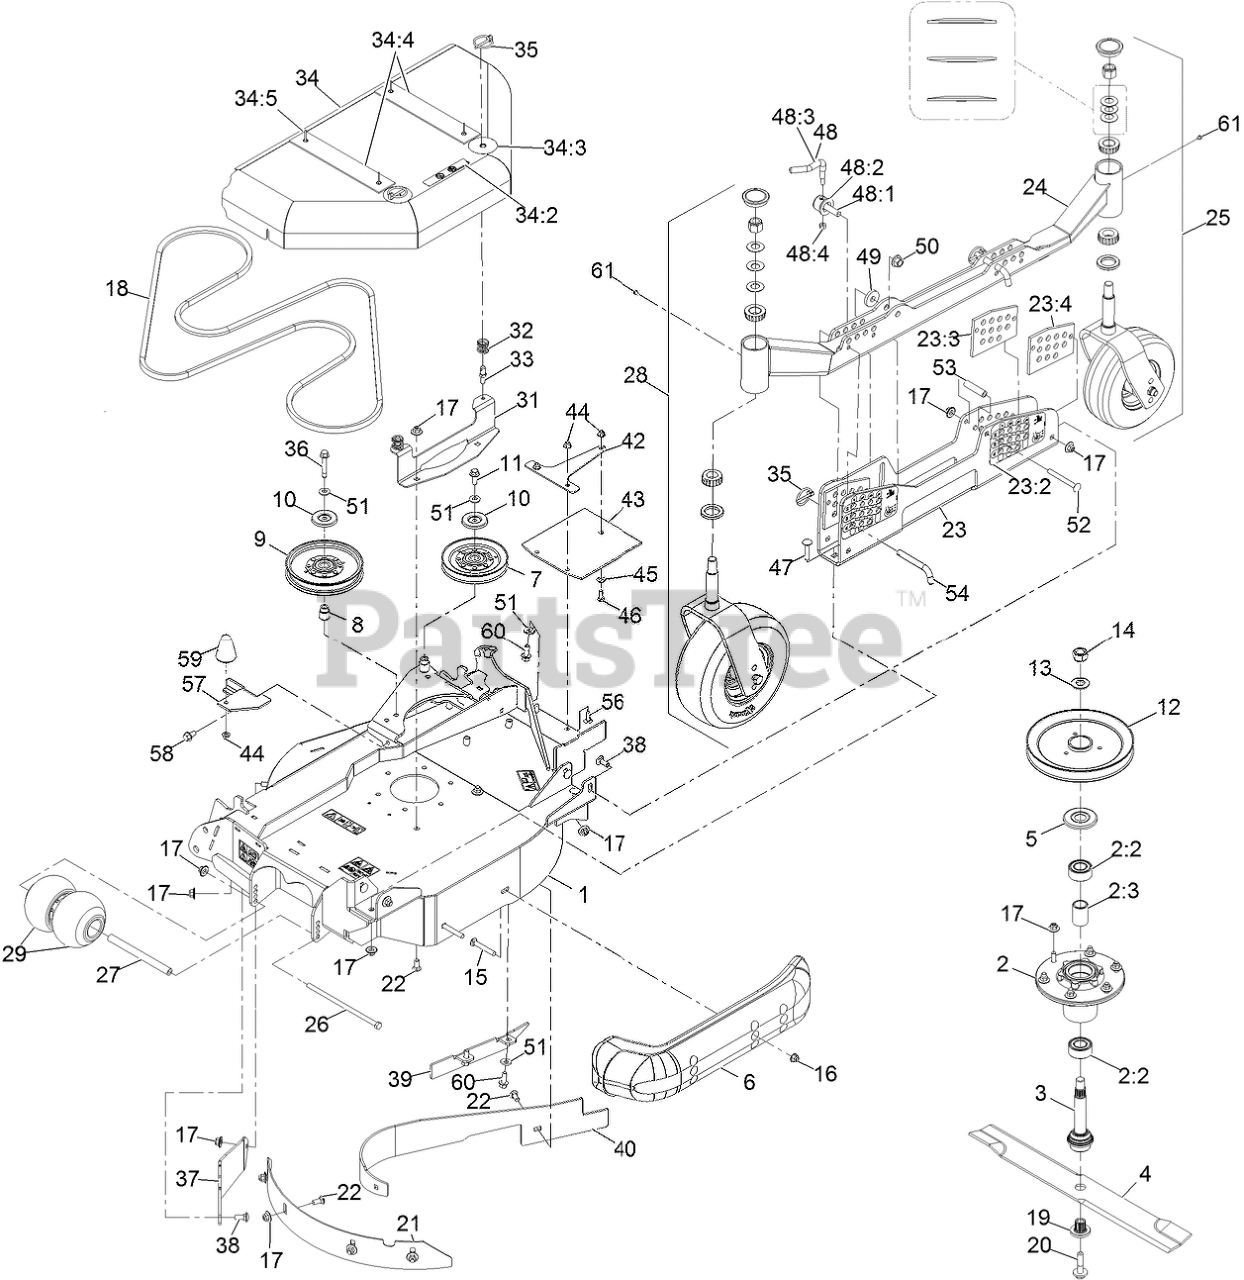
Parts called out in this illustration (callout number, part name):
1	ASM-Deck, LH Wing 96/120
2	ASM-Cutter Hsg
2:2	Bearing-3205 Trashguard
2:3	Spacer-Bearing
3	ASM-SPINDLE AND SEAL
5	GUARD-BEARING, TOP
6	SKID-BUMPER, DECK
7	IDLER-V
8	BUSHING-IDLER
9	IDLER-PULLEY
10	SHIELD-DUST
11	SCREW-HHF 3/8-16 X 1
12	SHEAVE-SINGLE 96RD
14	NUT-HEX
15	SCREW-CARR
16	NUT-HF, NI
17	Nut-Nyloc 3/8-16 Flg
19	BUSHING,SPLINED
20	SCREW,SEMS 1/2-20 X 2.19
21	BAFFLE-DEPTH, LH
22	BOLT-CARR
23	LH HOC CHANNEL ASM
23:2	DECAL-HEIGHT OF CUT-LH
23:3	PLATE-GUIDE, HOC (LH)
23:4	PLATE-GUIDE, HOC (RH)
24	TUBE-HOC, LH
25	Caster/Wheel ASM
26	SCREW-HH
27	SPACER-WHEEL
29	ROLLER-SCALP, ANTI
31	BRACKET-SHIELD MOUNT, OUT
33	PIN-SPRING
34	ASM-Wing Shield LH
34:2	DECAL-NO STEP
34:3	DECAL-SCRATCH COVER
34:4	Plate-Uhmw 2"
34:5	Rivet-Pop
35	PIN-LYNCH
36	SCREW-HHF W/ PATCH
37	PLATE-FILL, LH DECK
38	BOLT-CARR
39	Fin-Baffle, Discharge Wing (LH)
40	BAFFLE-DOGLEG, CENTER (RH
42	SUPPORT-FLAP, LH
43	GUARD-TIRE, LH
44	NUT-HF, NI
45	WASHER-PLAIN
46	SCREW-HH
47	SCREW-CARR
48	LEVER ASM
48:1	SCREW-LOCK
48:2	CAP-LOCK
48:4	NUT-LOCK, NI
50	Nut-Lock 1/2-13
51	WASHER-BELLEVILLE
52	SCREW-CARR
54	PIN-HOC
56	BOLT-CARR
57	BRACKET-COVER RETAINER
58	SCREW-HWH
59	BUMPER-RUBBER
60	SCREW-HHF
